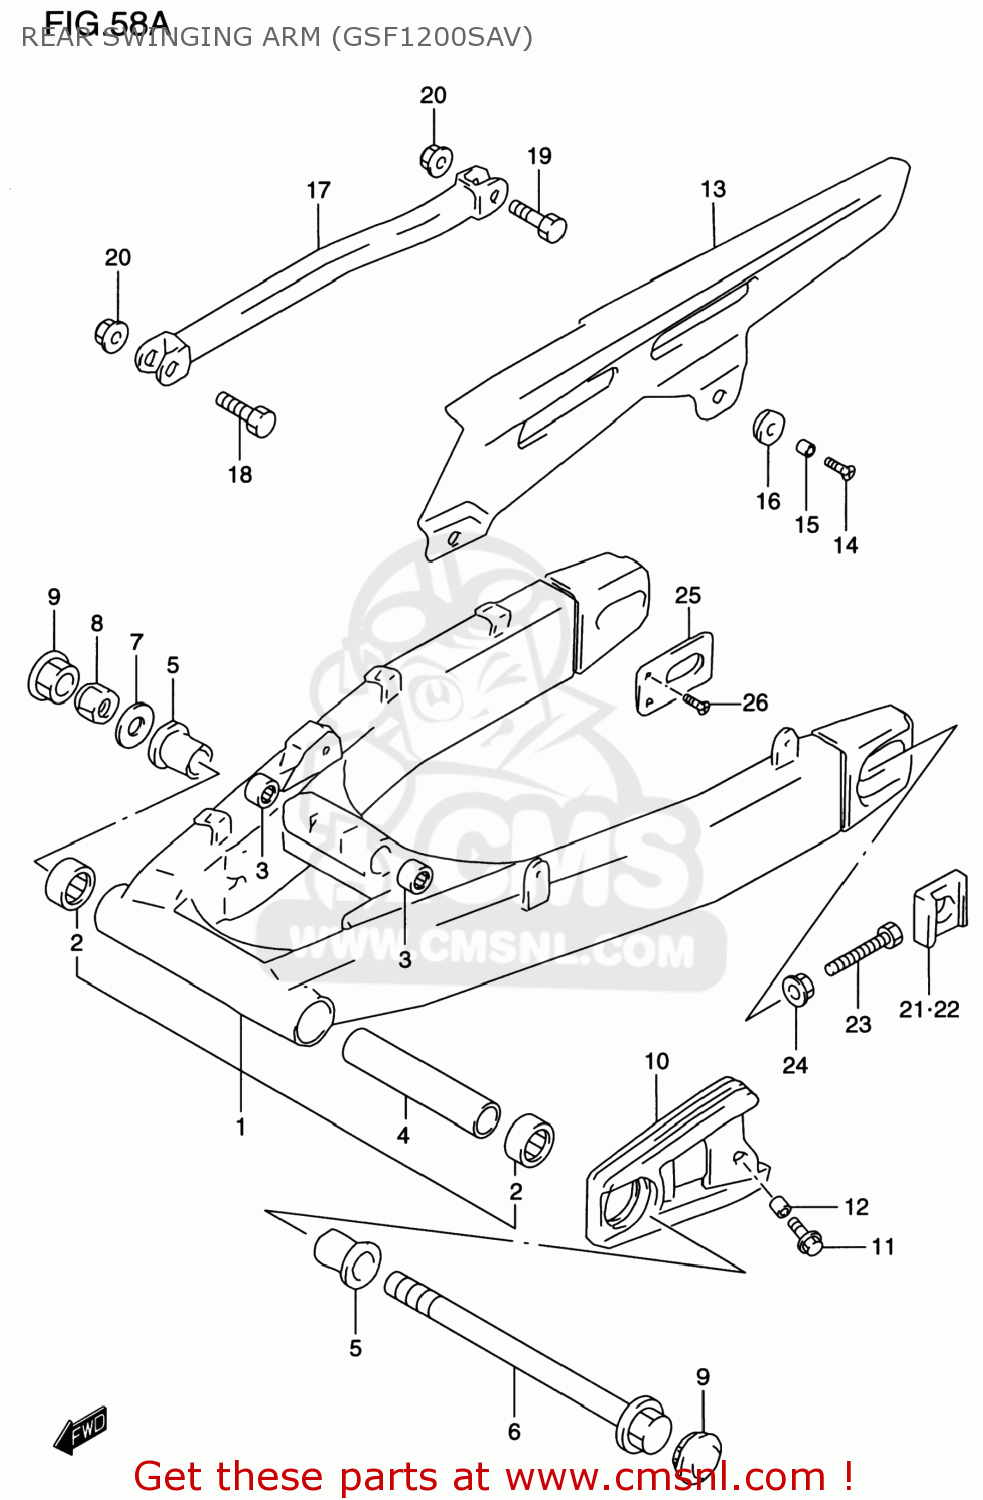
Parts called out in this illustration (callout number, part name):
1	SWING ARM ASSEMBLY,REAR
2	BEARING(25X33X35)
3	BEARING(17X24X25)
4	SPACER,RR SWGARM PIVOT CTR
5	SPACER,RR SWGARM PIVOT BERRING
6	SHAFT,RR SWINGINGARM PIVOT
7	WASHER(18.5X28X2.6)
8	NUT
9	CAP,FRAME PIVOT
10	BUFFER,CHAIN TOUCH DEFENSE
11	BOLT(6X20)
12	SPACER(6.5X10X7)
13	CASE,CHAIN
14	SCREW (6X16)
15	SPACER(6.2X8.3X6.1)
16	CUSHION
17	TORQUELINK,RR
18	BOLT(10X39)
19	BOLT(10X34)
20	NUT
21	WASHER,CHAIN ADJUSTER
22	WASHER,CHAIN ADJUSTER
23	BOLT(8X50)
24	NUT
25	PLATE,RR SWING ARM BRKT
26	SCREW
